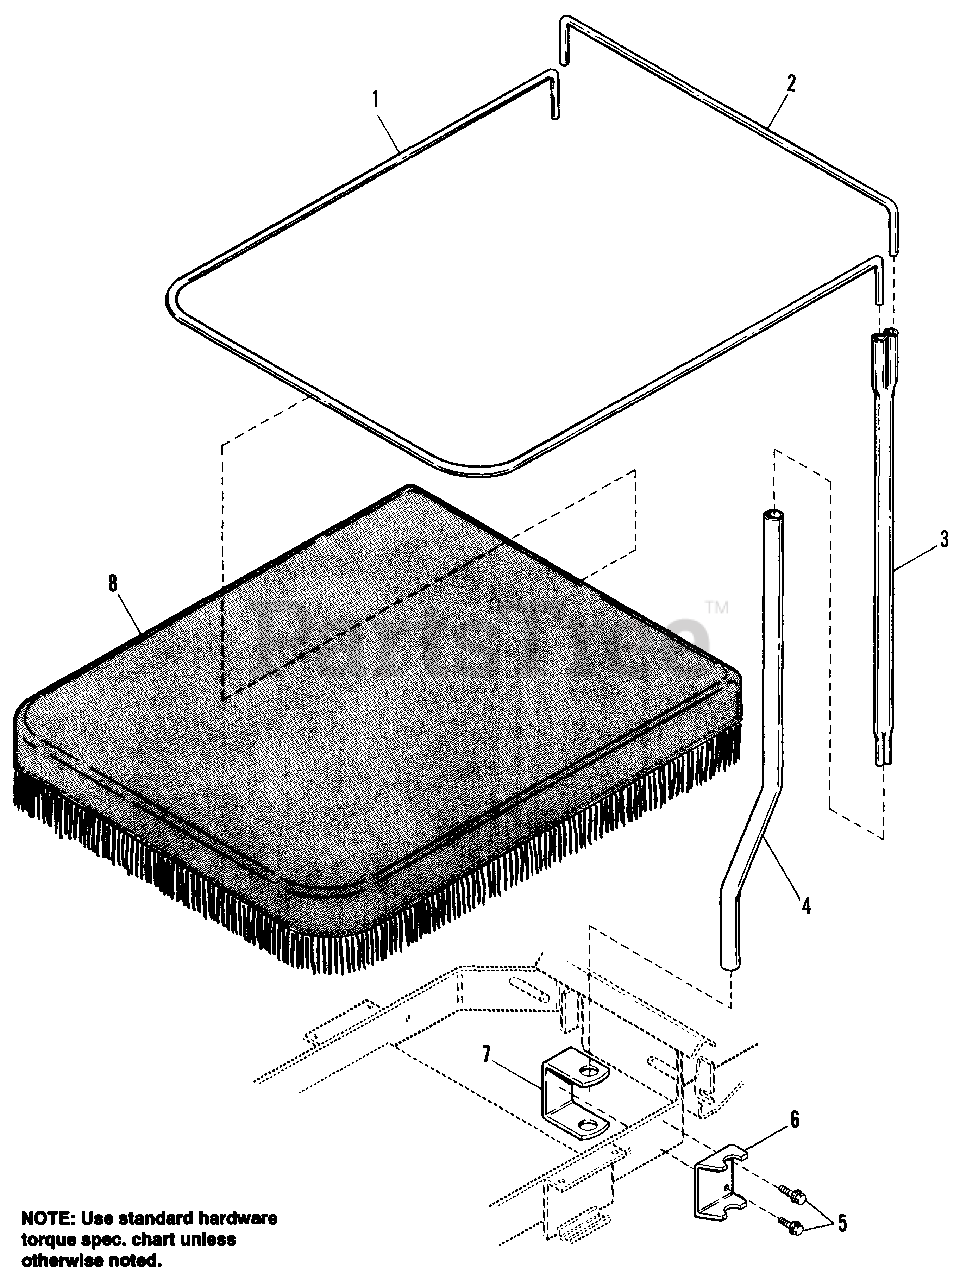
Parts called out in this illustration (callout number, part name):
1	FRAME, Cover, Front
2	FRAME, Cover, Rear
3	TUBE, Upright, Upper
4	TUBE, Upright, Lower
5	SCREW, Taptite, 1/4-20 x 3/4
6	BRACKET, Tube
7	CLAMP, Tube
8	COVER, Fabric, Surrey
